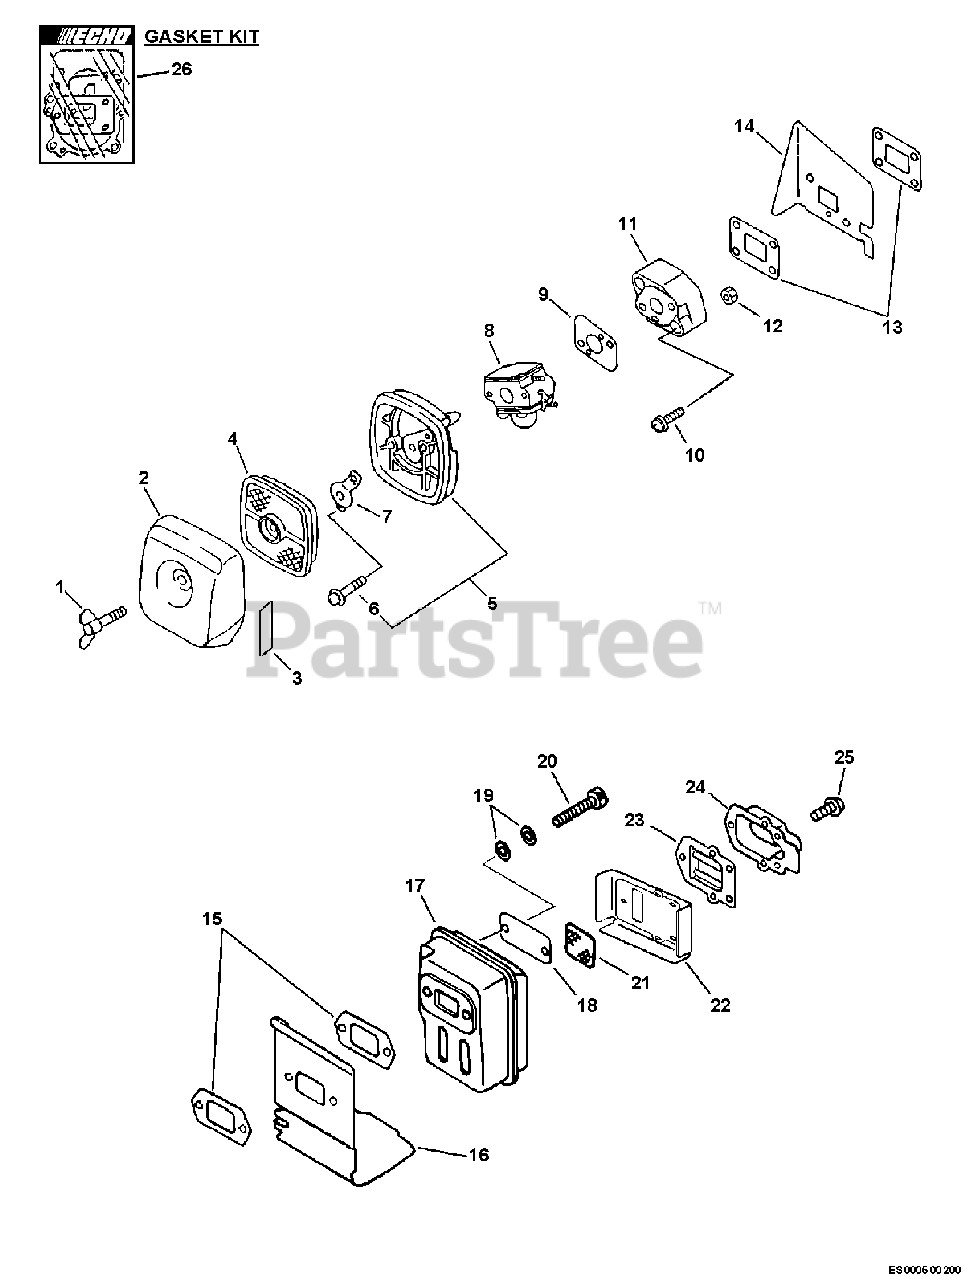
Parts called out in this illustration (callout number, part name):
1	BOLT, WING 5×20
2	COVER, AIR FILTER - GRAY
3	LABEL, CHOKE
4	FILTER, AIR - SINGLE LAYER
5	AIR FILTER CASE ASSY
6	SCREW 5×65
7	PLATE, PREVENT
8	CARBURETOR - C1U-K62
9	GASKET, INTAKE
10	SCREW 5×22
11	INSULATOR, INTAKE
12	NUT M5
13	GASKET, INTAKE
14	HEAT SHIELD, INTAKE
15	GASKET, EXHAUST
16	COVER, MUFFLER
17	MUFFLER
18	PLATE, EYE
19	CONICAL WASHER
20	BOLT 5×55
21	SCREEN, SPARK ARRESTER
22	GASKET, EXHAUST
23	GUIDE, EXHAUST - INNER
24	GUIDE, EXHAUST
25	SCREW 4×12
26	GASKET KIT
